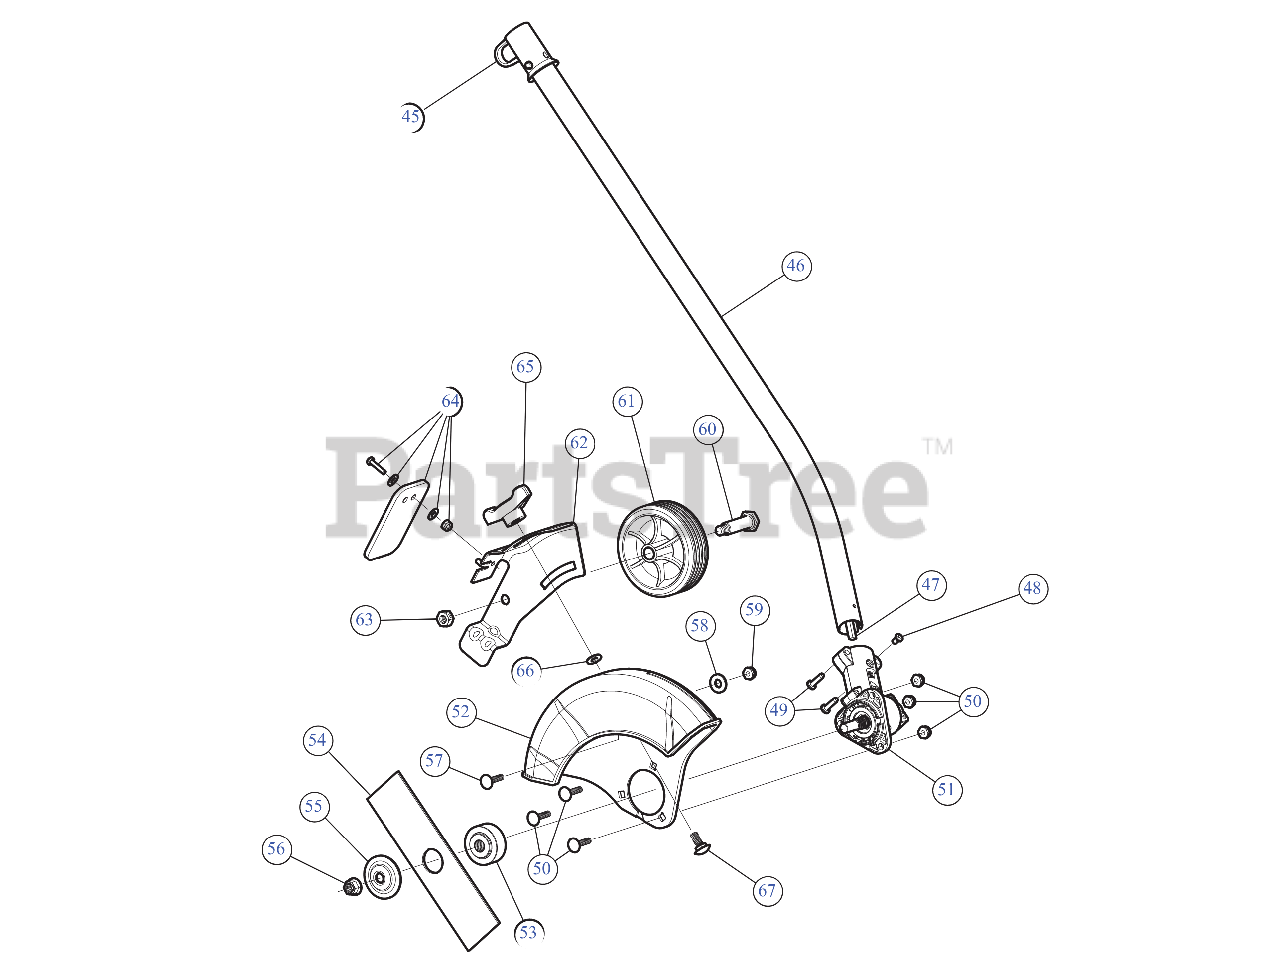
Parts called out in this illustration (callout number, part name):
45	HANGER
46	BOOM ASSEMBLY LE
47	LOWERIBLE DRIVE SHAFT
48	SCREW, 8-32 x .312 P
49	SCREW #
50	HDWR ASM:GUARD MT
51	GRBX ASSEMBLY
53	SPACER
54	EDGER BLADE
55	WASHER-BLADE CLAMP BRUSH CUT
56	BLADE LOCK NUT
57	BOLT:WHEEL MT BRACKET
58	WASH, FLAT .734 OD
59	NUT 1/4-20 NYLOC
60	BOLT
61	WHEEL 3.75" (WHITE)
62	BRACKET GUARD
63	LOCK NUT 3/8-16
64	DEFLECTOR W/HDW
65	WING KNOB 5/16-18
66	WASHER .406X1.0X.095
67	CARRIAGE BOLT 5/16-18 x .75
